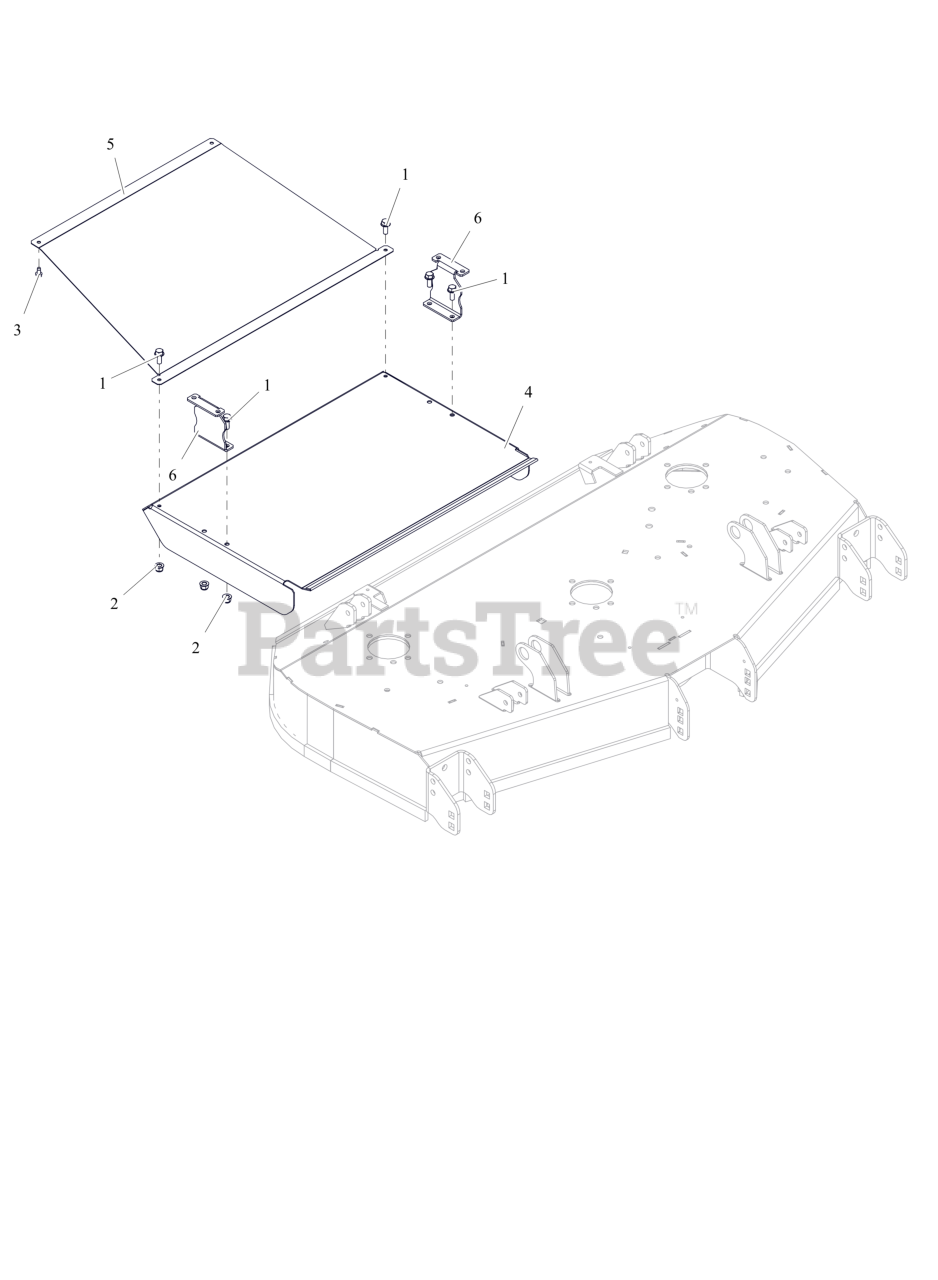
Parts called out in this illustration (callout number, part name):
1	M8 x 20 Flange Bolt
2	NUT, FLANGED M8
3	SCR-TAP .25-20X.50 HWH ZCC
4	DEFLECTOR, TRANSAXLE APEX
5	DEFLECTOR, UNDERBODY
6	BRKT, DEFLECTOR SUPPORT
